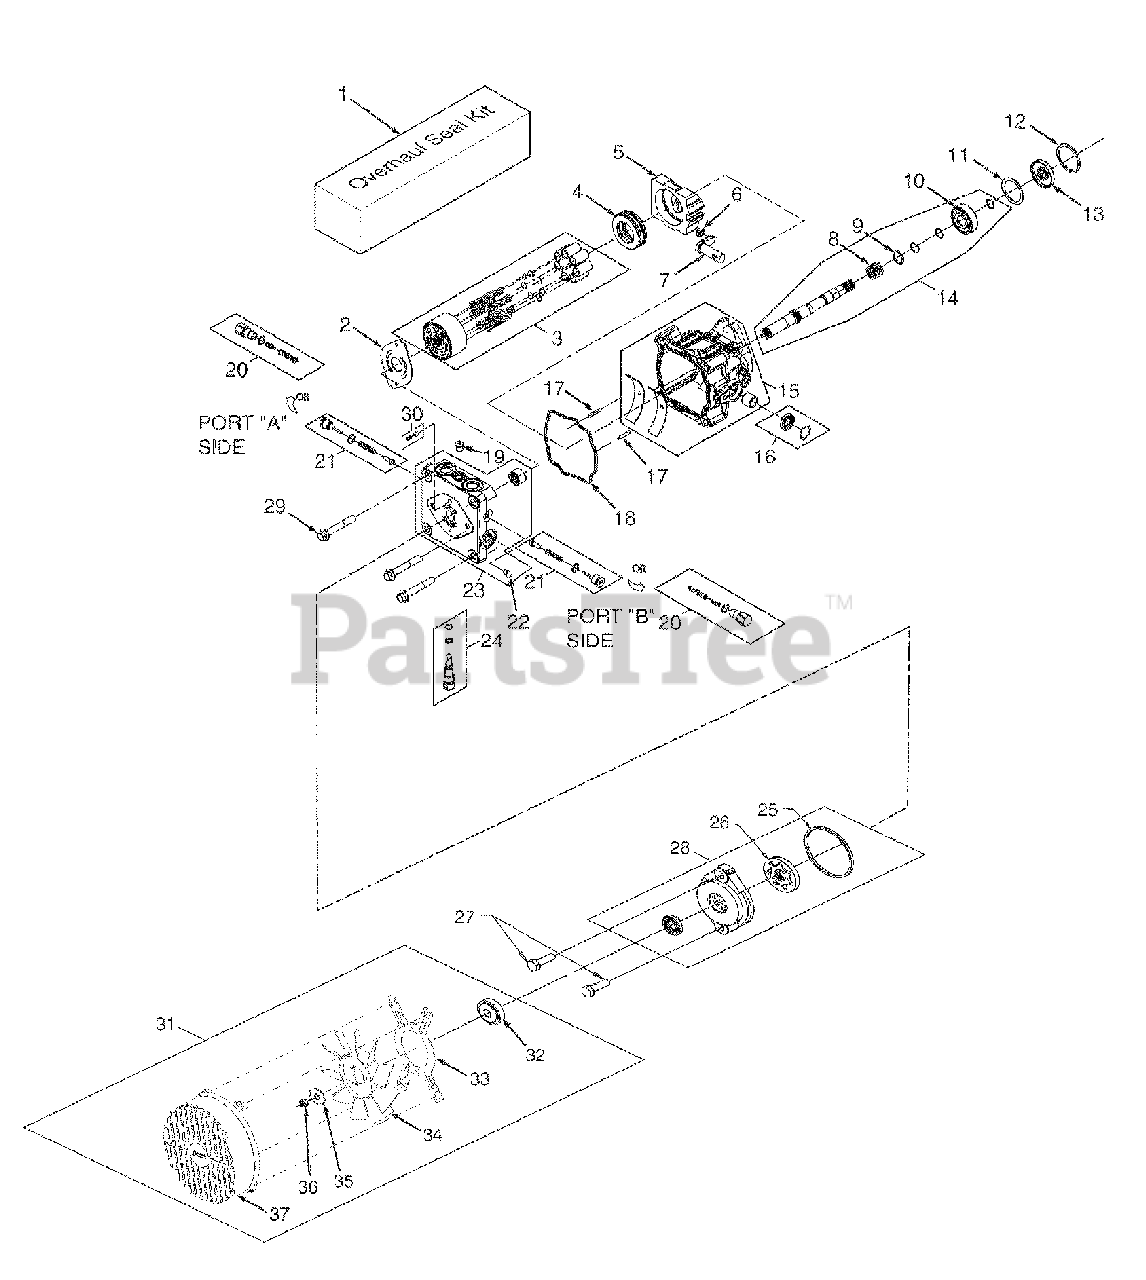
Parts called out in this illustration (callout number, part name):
1	Overhaul Seal Kit
2	Valve Plate
3	Cylinder Block Kit - 16cc
4	Thrust Ball Bearing Assembly
5	Variable Swashplate
6	Slot Guide
7	Trunnion Arm
8	Block Spring
9	Block Thrust Washer
10	Shaft Ball Bearing
12	Retaining Ring
14	Kit, Pump Shaft
15	Housing Kit
16	Trunnion Seal Kit
18	O-Ring
19	Straight Thread Plug
20	Shock Valve Kit
21	Shock Valve Kit
22	Straight Thread Plug
23	End Cap Kit
24	Bypass Valve Kit
26	Gerotor Assembly
27	Socket Head Cap Screw
28	Charge Pump Kit
29	Hex Screw, Flanged Head
30	Charge Relief Kit
31	Fan Kit
33	Bracket, Shroud
35	Washer
37	Shroud
